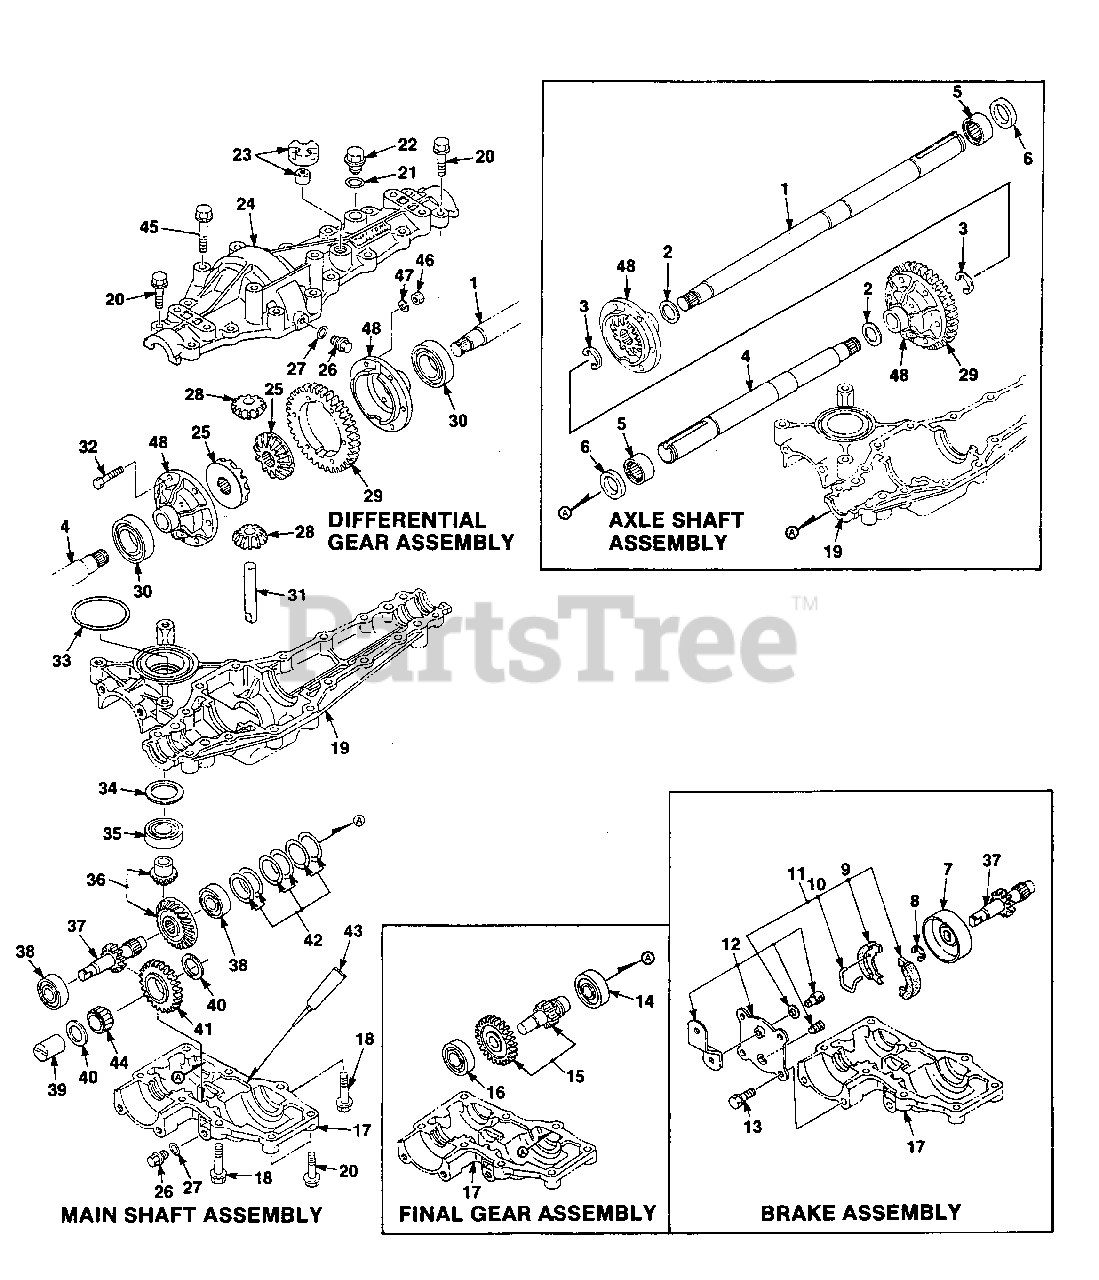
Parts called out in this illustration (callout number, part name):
1	AXLE & SHAFT (R)
2	WASHER- (20 x 29.5 x 2)
3	RING- (15)
4	AXLE- Shaft
7	DRUM- Brake
8	RING- (10)
9	SHOE- Brake
11	BRAKE- Assy (CB-1)
12	BRAKE COVER ASSY.
13	BOLT- (w/washer) (8 x 20)
14	BEARING (6203)
15	FINAL PINION ASSY.
16	BEARING- (6302)
17	CASE- Lower
18	SCREW- Tapping (8 x 35)
19	MISSION CASE
20	SCREW- Tapping (8 x 30)
21	PACKING- (P16)
22	PLUG- (14)
23	VENT VALVE ASSY.
24	UPPER CASE
25	GEAR- Differential
28	PINION- Differential
29	GEAR- Final (43)
30	BEARING- (6006)
31	SHAFT- Diff. Pinion
32	BOLT- (6 x 30)
33	PACKING- (G60)
34	WASHER- (.30 x 42 x 2)
35	BEARING- (6004)
36	MOTOR GEAR ASSY
37	MAIN SHAFT
38	BEARING- (6202)
39	SHAFT- Idle
40	WASHER- Thrust
41	GEAR- (24)
42	SHIM- ASSY.
44	NEEDLE- (20 x 26 x 12)
45	SCREW- Tapping (8 x 45)
